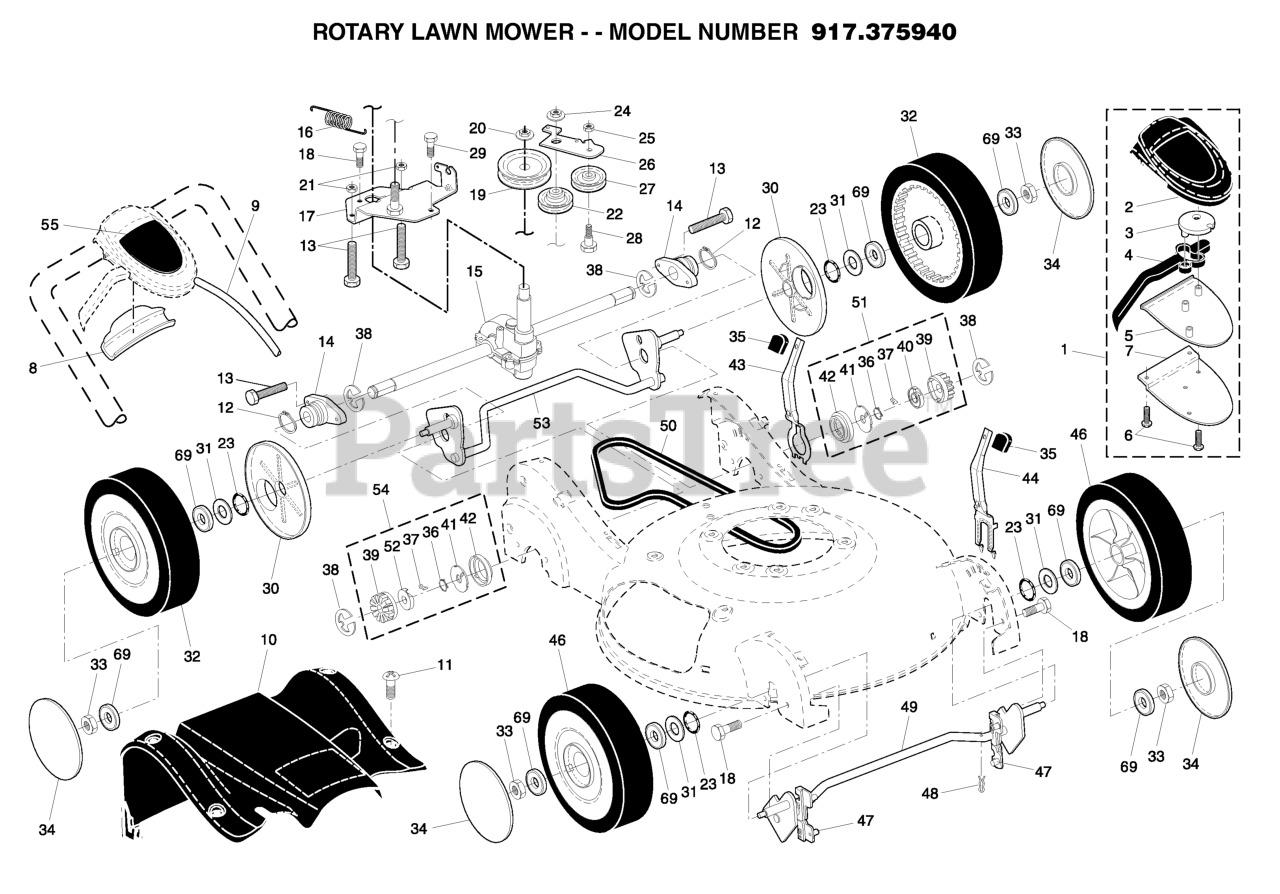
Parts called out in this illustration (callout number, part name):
1	CONTROL.DR.HV.RWGD.GRY/BLU
2	CASE.TOP.GRAY
3	PULLEY.CAM.DRIVE.CONTROL.HV
4	LEVER
5	CASE BOTTOM
6	SCREW, PHILLIPS HEAD 10 X 5/8
7	BRACKET, DRIVE CONTROL
8	EZ WALK SNAP COVER PLATE
9	ASM.CABLE.
10	COVER ASSEMBLY, DRIVE
11	SCREW
12	RETAINING RING (2 2)(3 2)
13	RP SCREW
14	BEARING.SUPPORT.ASSEM
15	TRANSMISSION.21.HI-VAC.EZ
16	SPRING.RETURN
17	BRKT.TRANSMISSION.HV.E
21	NUT
22	PULLEY.IDLER.V-BELT
23	O-RING
24	NUT
25	NUT.CENTERLOCK.5/16-
26	ARM.IDLER.BZP
27	IDLER PULLEY
28	SHOULDER BOLT
29	SCREW 14-20 X 5/8
30	DUST COVER, WHEEL
31	WASHER.FLAT.1/2
32	WHEEL.9X2.25.PR.JUNG.BLK
33	HEX FLANGE LOCKNT
34	RB HUBCAP.3-SPOKE.SILVER
35	KNOB.SELECTOR.SPRG.H-GRY (2 2)
36	SPRING, TORSION
37	PAWL.DRIVE.21.EZ-WALK
38	E-RING 7/16 RE
39	GEAR, PINION
40	RETAINER.DRIVE.21.EZ-WALK.LT
41	DISC.DRIVE.21.EZ-WALK
42	SEAL.PINION
43	LEVER, SELECTOR, HEIGHT, REAR
44	LEVER, SELECTOR, HEIGHT, FRONT
46	WHEEL.9X2.25.LP.JUNG.BLACK
47	BUSHING.FRONT.TORQUE.SHAFT
48	SPRING RETAINER
49	SHAFT FRONT
50	BELT.DRIVE.EZ.WALK.HI-VAC
51	PINION ASSY, LH
52	RETAINER, DRIVE, RH
53	AXLE.ASM.REAR.TORQUE.BZP
54	PINION ASSY, RH
55	DECAL.DRIVE.CONTROL.HV
69	BEARING, BALL
